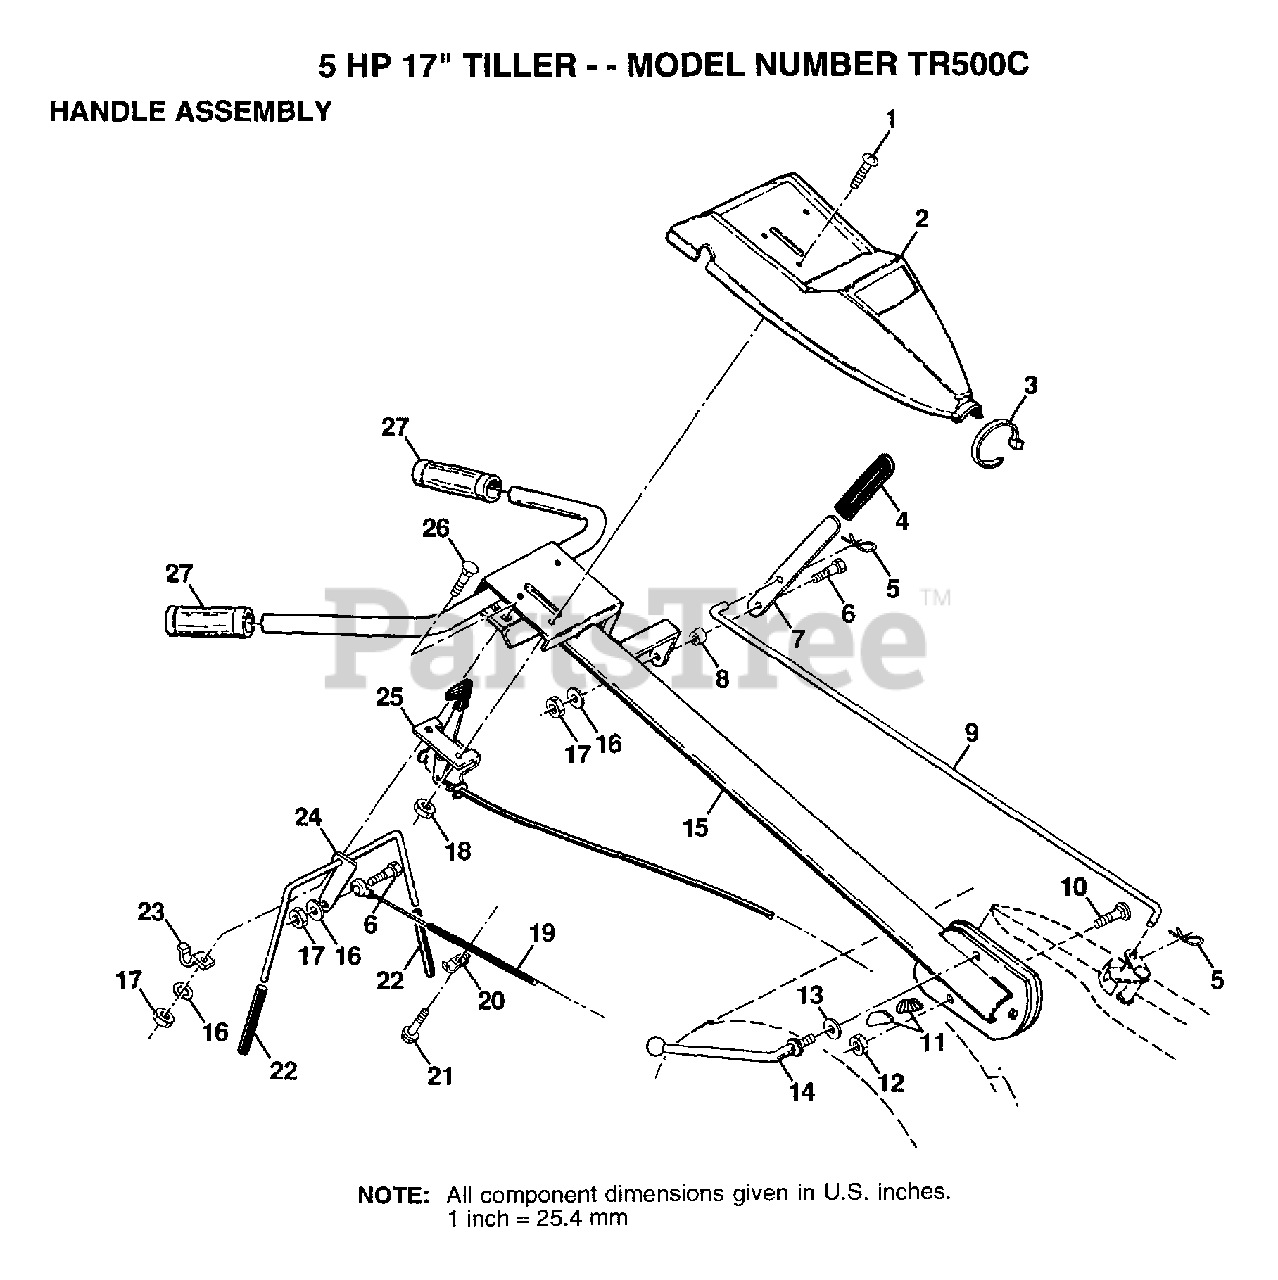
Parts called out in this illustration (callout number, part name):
1	SCREW
2	"PANEL,CONT TI"
3	TIE CABLE CRT
4	GRIP T
5	RETAINER M
6	SHOULDER BOLT ST
7	SHIFT HANDLE CRT
8	GROMMET CRT
9	SHIFT ROD CRT
10	BOLT D
11	LOCK CRT
12	LOCKNUT
13	WASHER CRT
14	LEVER LOCK CRT
15	HANDLE.ASM
16	LOCKWASHER
19	CABLE.CLUTCH.CRT
20	CONDIUT CLIP T
22	GRIP BAR CRT
24	"ASSY CONTROL, BAR"
25	"CONT,THROTTLE"
26	BOLT
